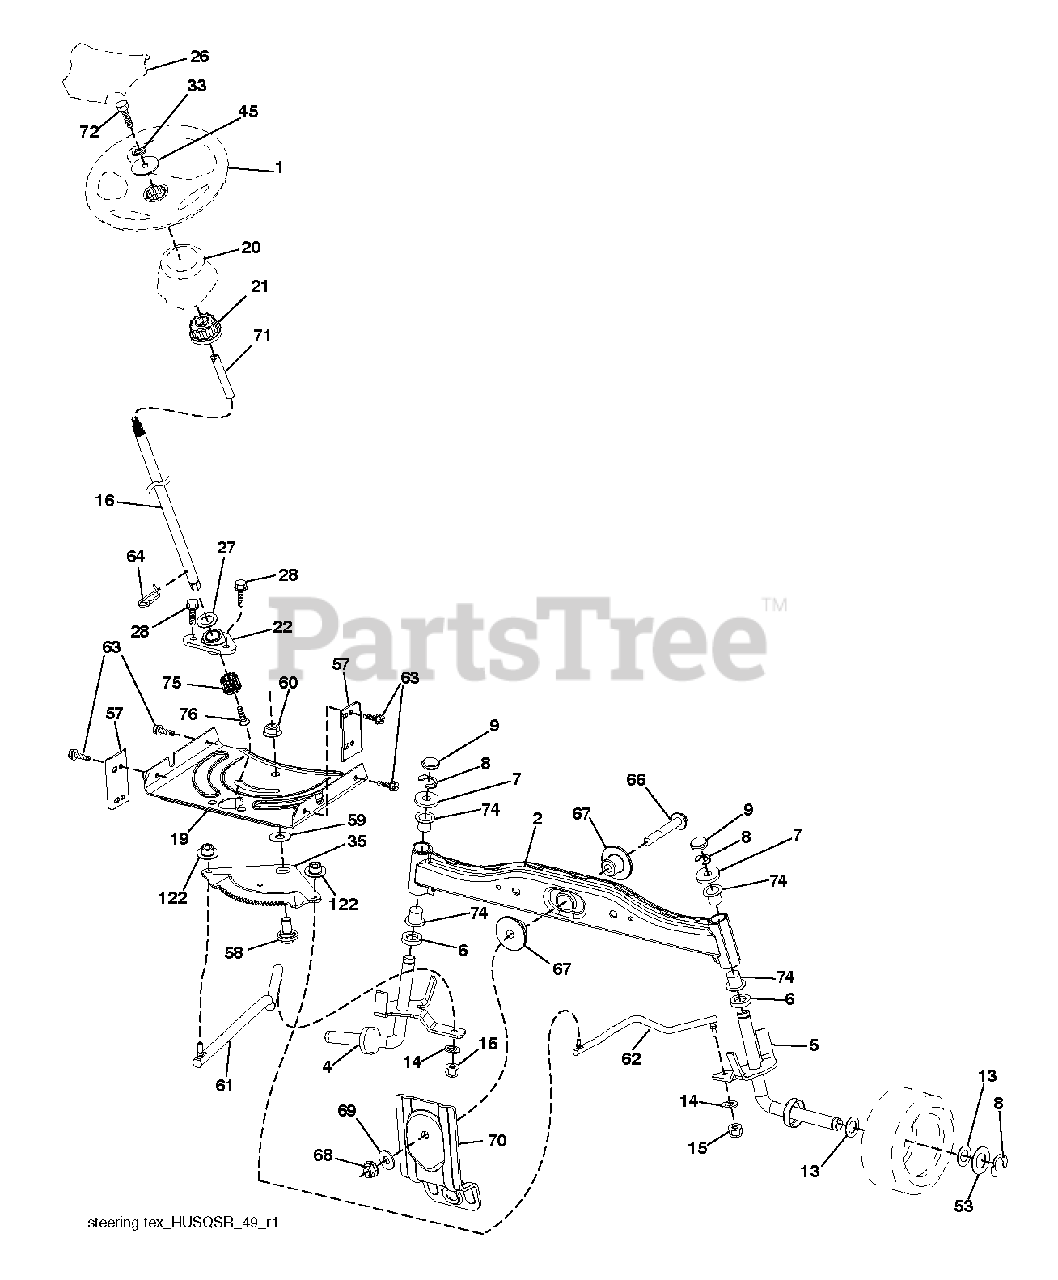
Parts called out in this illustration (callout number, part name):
1	WHEEL.STEERING.HUSQ.PREM.HRDRM
2	AXLE HALF ASM-WELDED
4	SPINDLE.WELDED.LH.15"TEX
5	SPINDLE.WELDED.RH.15"T
6	THRUST WASHER
9	CAP.SPINDLE.BLACK
14	SLW 3/8 STD
15	NUT CROWNLOCK 3/8-24
16	3 HIGH.SHAFT-ZINC.PLATED
19	PLATE.STEER.DDL.NLT/NG
20	STEERING.BOOT.HUSQ.LT
21	ADAPTER, WHEEL STNG..
22	BEARING.SHAFT.STEER.LOWER.625
26	INSERT.CAP.WHL.STRG.HUSQ.PREM
27	WASHER LT
28	SCREW, 3/8-16X3/4
33	WASHER 5/16 LOCK
35	GEAR.SECTOR.PLATE.DDL.
45	WASHER.11/32
53	WASHER.HARDENED
57	BRACKET.UPSTOP.TEX
58	BOLT.SHOULDER.SECTOR.P
59	WASHER.THURST.SECTOR.S
60	NUT FLANGE LOCK 5/8-11
61	DRAGLINK.LH.BALLSTUD.D
62	DRAGLINK.RH.BALLSTUD.D
63	SCREW
64	RETAINER.CLIP.SPRING.S
66	BOLT HEX FGHD 7/16-14 X 3 SERR
67	BUSHING.PM.FRONT AXLE
68	NUT.LOCK.FLANGE.7/16
69	WASHER.1.5X.505X.118
70	BRACKET.FRT.DECK.SUSP.RR.MT431
71	SHAFT.EXTEN.STRG.SPLINE
72	BOLT 5/16-18 X 4 W/PATCH
74	BRNG T
75	PINION.ZINC PLATED
76	SCREW HEAD SOCKET LRVB
122	CAP.GEAR.SECTOR.TEX
